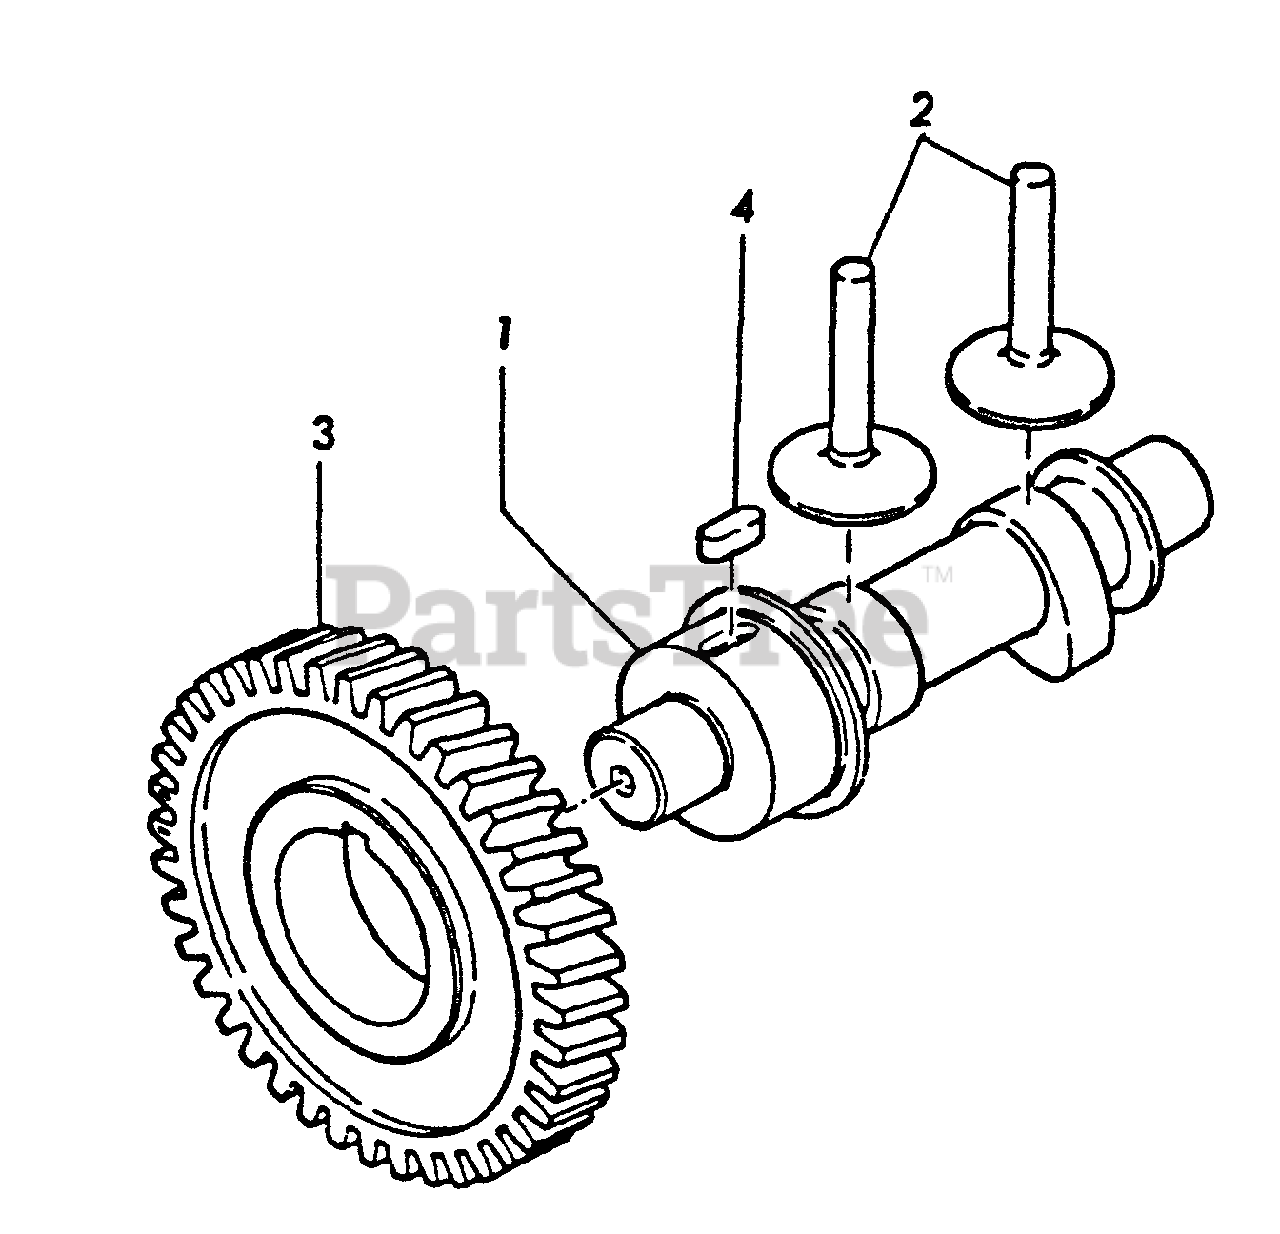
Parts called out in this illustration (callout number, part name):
1	CAMSHAFT
2	TAPPET
3	GEAR, CAMSHAFT
4	KEY - 4X12
